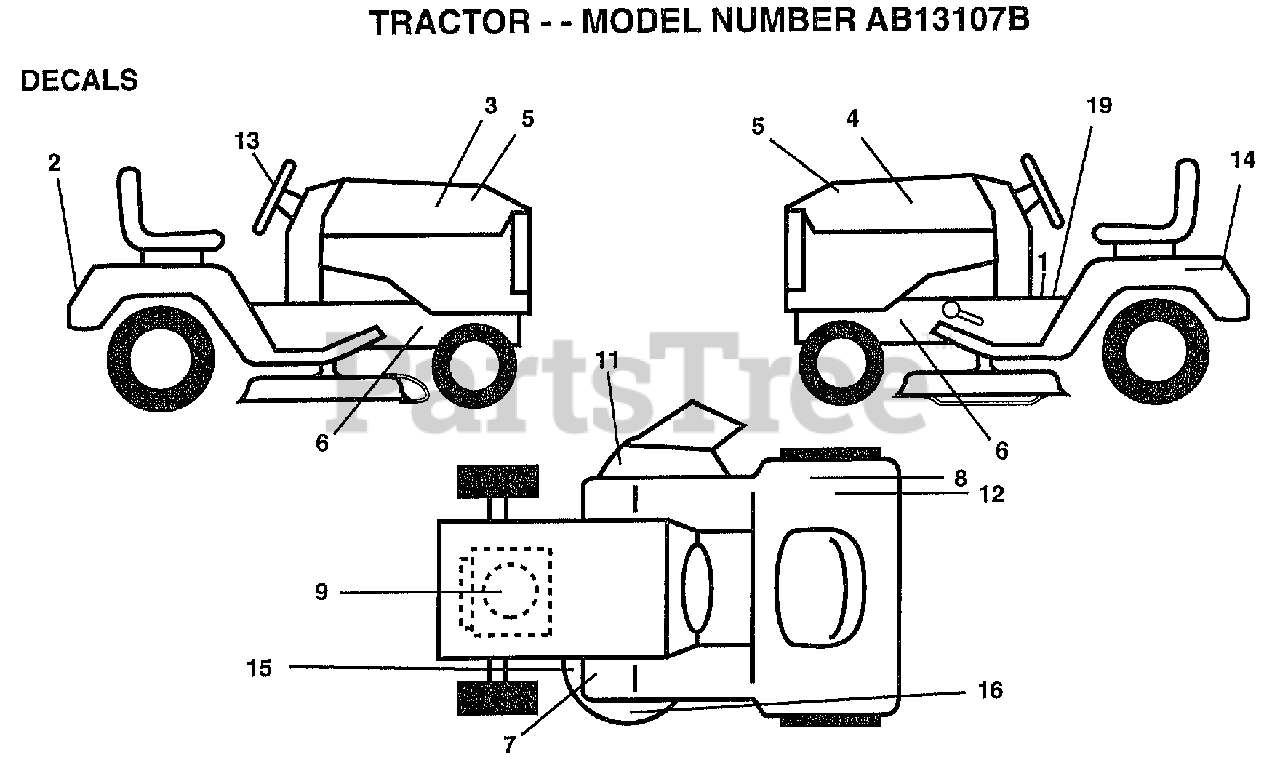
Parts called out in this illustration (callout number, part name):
1	DECAL.READ.O.MANU
2	DECAL.LOGO FENDER
3	DECAL.HOOD.RH
4	DECAL.HOOD.LH
5	DECAL.PNL.SIDE.BS
6	"DECAL CHASSIS,HOT"
7	DECAL-BRAKE/CLUTC
8	DECAL.EURO.ST.CE.
9	DECAL.HP.ENG.B&S13HP
11	DECAL.DANGER.CUTF
13	DECAL.INS.STRG.WH
14	DECAL.BATRY.3-3908
15	"DECAL-SCHEM,BELT"
19	DECAL BRAK PARK
